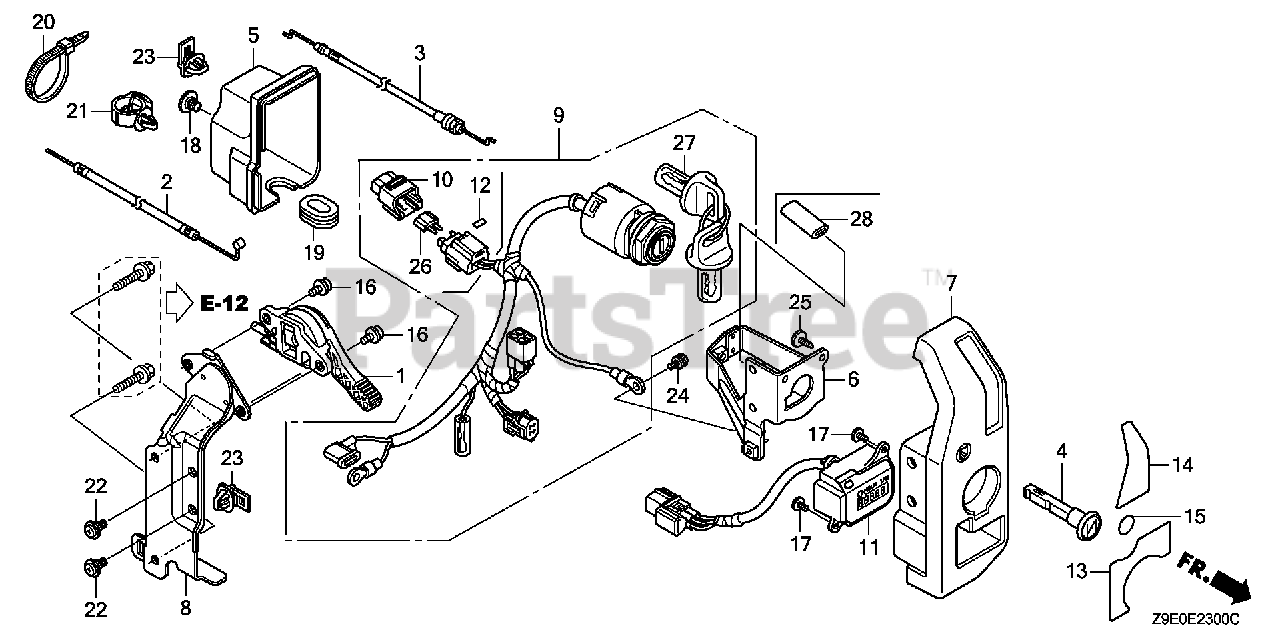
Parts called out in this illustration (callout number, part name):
1	LEVER ASSY., THROTTLE
2	CABLE, THROTTLE
3	CABLE, CHOKE
4	KNOB, CHOKE
5	COVER, CONTROL
6	BRACKET, SWITCH BOX
7	PANEL, CONTROL
8	BRACKET, CONTROL BOX
9	SWITCH ASSY., COMBINATION
10	COVER ASSY., FUSE
11	METER ASSY., HOUR
12	LABEL, FUSE (30A)
13	MARK, ENGINE SWITCH
14	MARK, THROTTLE SWITCH
16	BOLT, SOCKET (5X9)
17	SCREW, TAPPING (3X8) (PO)
18	SCREW, SPECIAL (6X8)
19	GROMMET, CONTROL BOX
20	BAND, WIRE (95MM)
21	CLIP, WIRE HARNESS
22	SCREW, PAN (5X10.5)
23	CLIP, CONNECTOR (BLACK)
24	SCREW-WASHER (5X8)
25	SCREW, TAPPING (5X14) (PO)
26	FUSE, MINI (30A)
27	KEY ASSY., COMBINATION SWITCH (W05)
